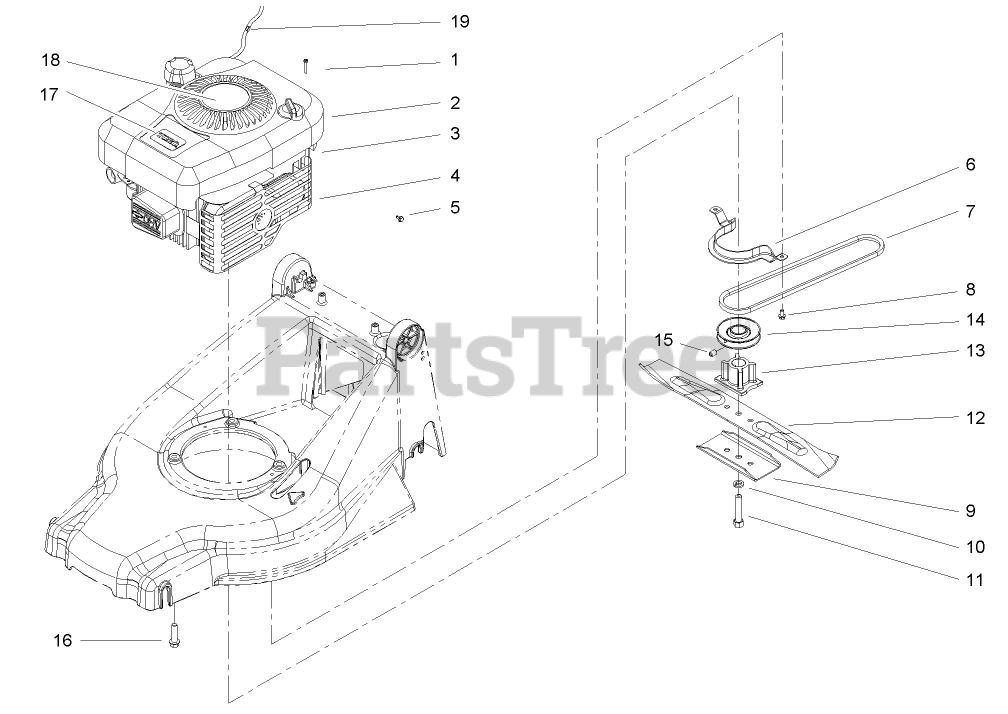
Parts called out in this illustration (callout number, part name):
1	SCREW-PPH, PLASTITE
2	SHROUD-QUANTUM
3	Loose Parts Package
4	SHIELD-MUFFLER
5	SCREW-HWH
6	GUIDE-BELT, ENGINE
7	V-BELT
8	SCREW-HWH
9	STIFFENER-BLADE
10	WASHER-LOCK
11	BOLT-BLADE
12	BLADE-48 CM
13	RETAINER-BLADE
14	PULLEY ASM
16	SCREW-HWH
17	DECAL
19	STOP-ROPE
